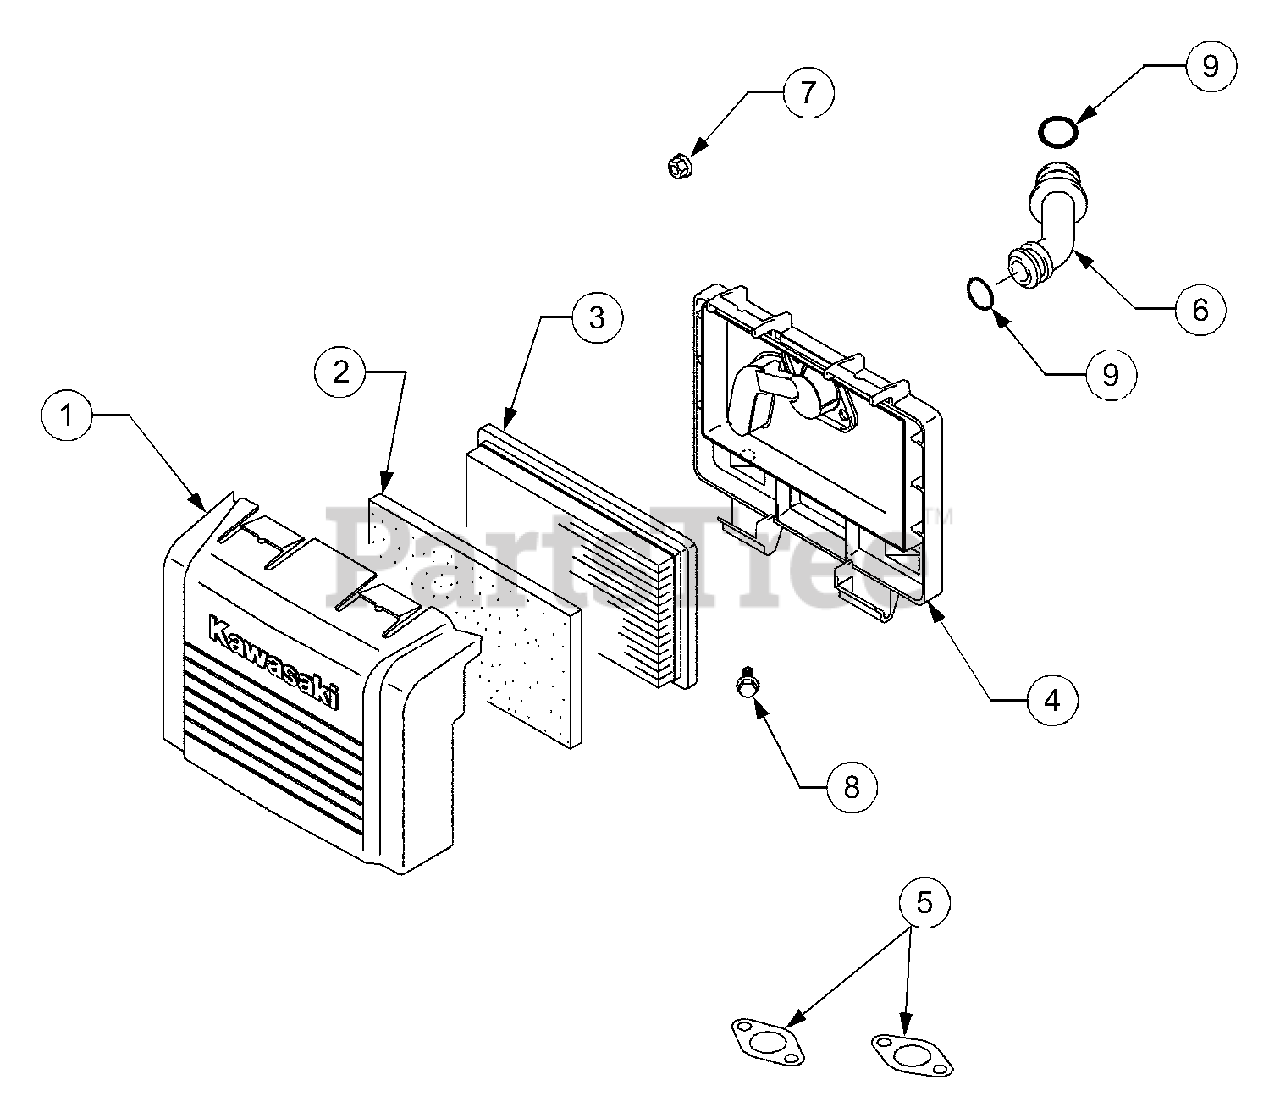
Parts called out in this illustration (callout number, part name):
1	Case, Air Filter Upper
2	Element, Air Filter
3	Element, Air Filter
4	Case Assy, Air Filter Lower
5	Gasket, Muffler
6	Pipe, Breather
7	Nut
9	O-Ring,10mm
